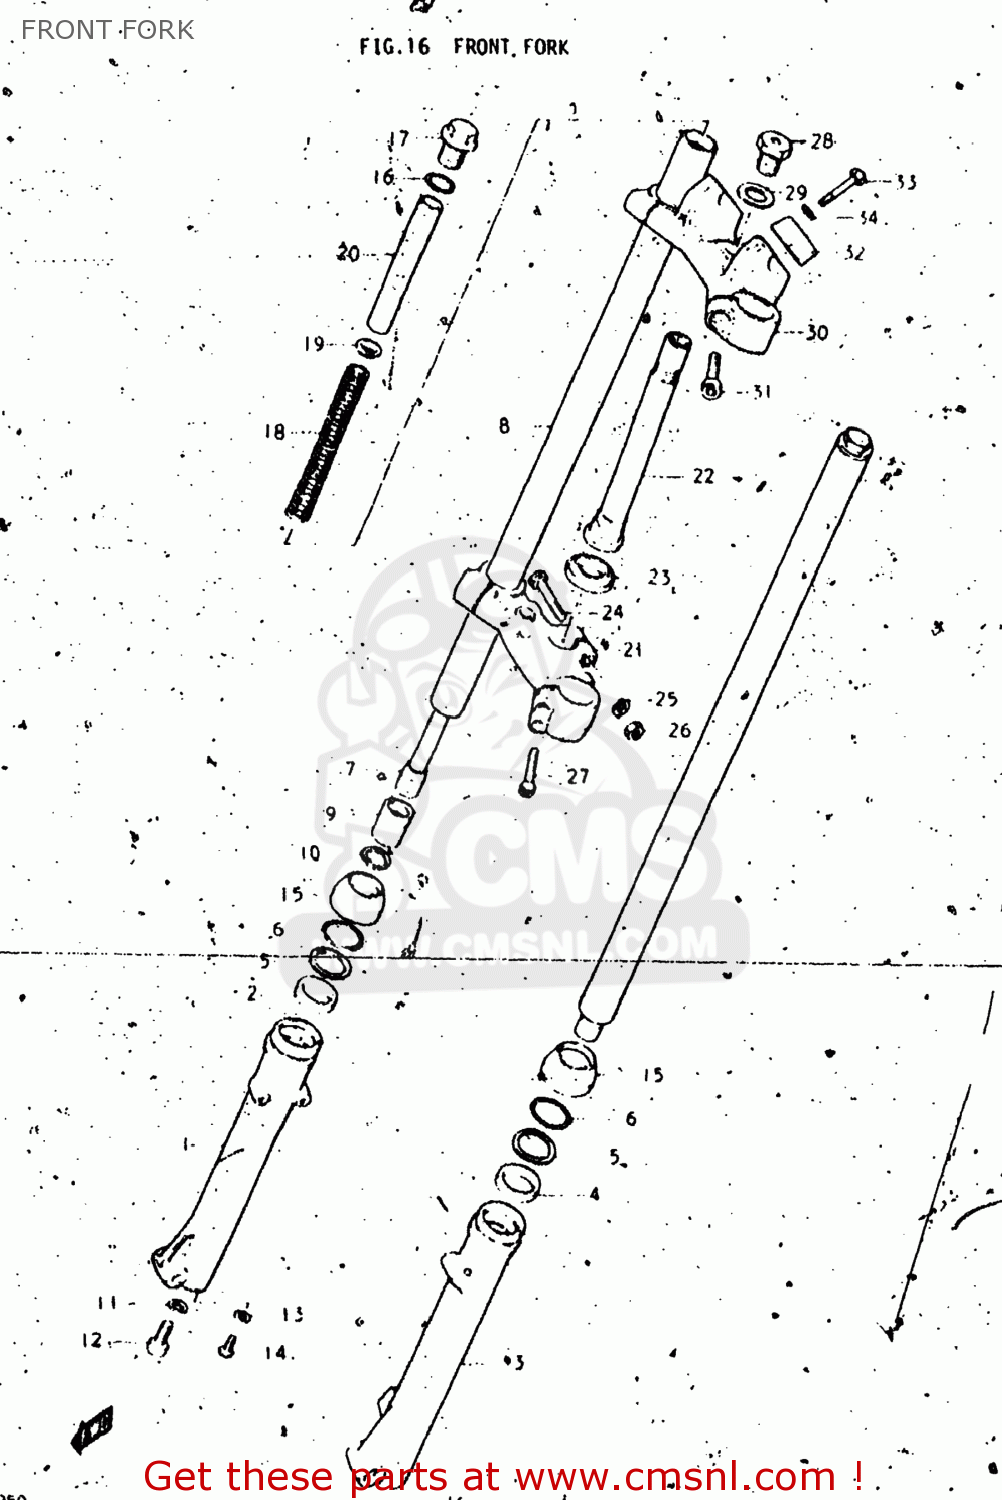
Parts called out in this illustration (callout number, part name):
1	TUBE,OUTER,RIGHT
2	SEAL,OIL
3	TUBE,OUTER,LEFT
4	SEAL,OIL
5	RING,FORK BACK UP
6	CIRCLIP,FORK OIL SEAL
7	CYLINDER,FRONT FORK
8	TUBE,FORK,INNER
9	PISTON,FORK INNER TUBE
10	RING
11	GASKET (NAS)
12	BOLT,FORK CYLINDER(10X25)
13	GASKET,DRAIN,PLUG (NAS)
14	SCREW
15	SEAL,DUST
16	O RING
17	BOLT,FORK
18	SPRING,FRONT FORK
19	GUIDE,FRONT FORK SPRING C
20	COLLAR,SPRING
21	STEM,STEERING
22	STEM,STEERING
23	RACE,STEERING OUTER LWR
24	BOLT
25	LOCK WASHER
26	NUT
27	BOLT
28	CAP
29	WASHER,STEM HEAD
30	HEAD,STEERING STEM
31	BOLT
32	HOLDER,HANDLEBAR
33	Bolt
34	LOCK WASHER
